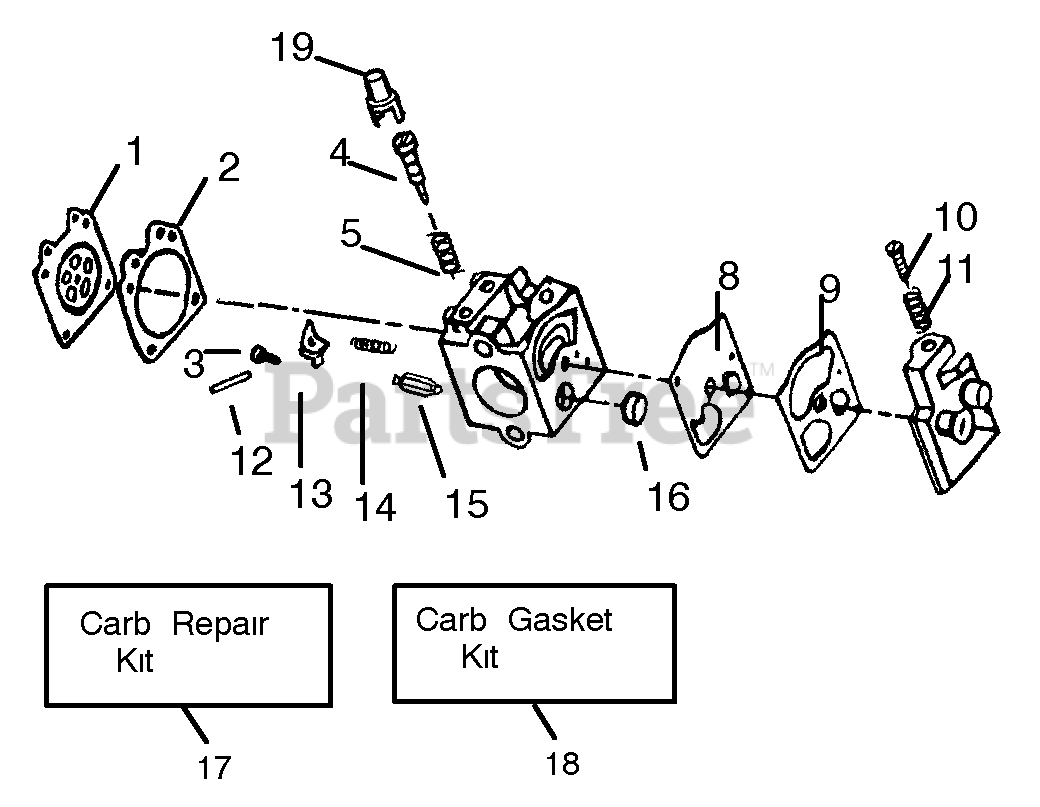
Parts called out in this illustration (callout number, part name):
1	DIAPHRAGM
2	Metering Diaphragm Gasket
3	Metering Lever Pin Screw
4	Mixture Needle
5	Mixture Needle Spring
8	Fuel Pump Diaphragm
9	Fuel Pump Gasket
10	Idle Speed Screw
11	Idle Speed Spring
12	Metering Lever Pin
13	Metering Lever
14	Metering Lever Spring
15	Inlet Needle Valve
16	Fuel Inlet Screen
17	Carb. Kwik Repair Kit
18	Carb. Gasket/Diaphragm Kit
